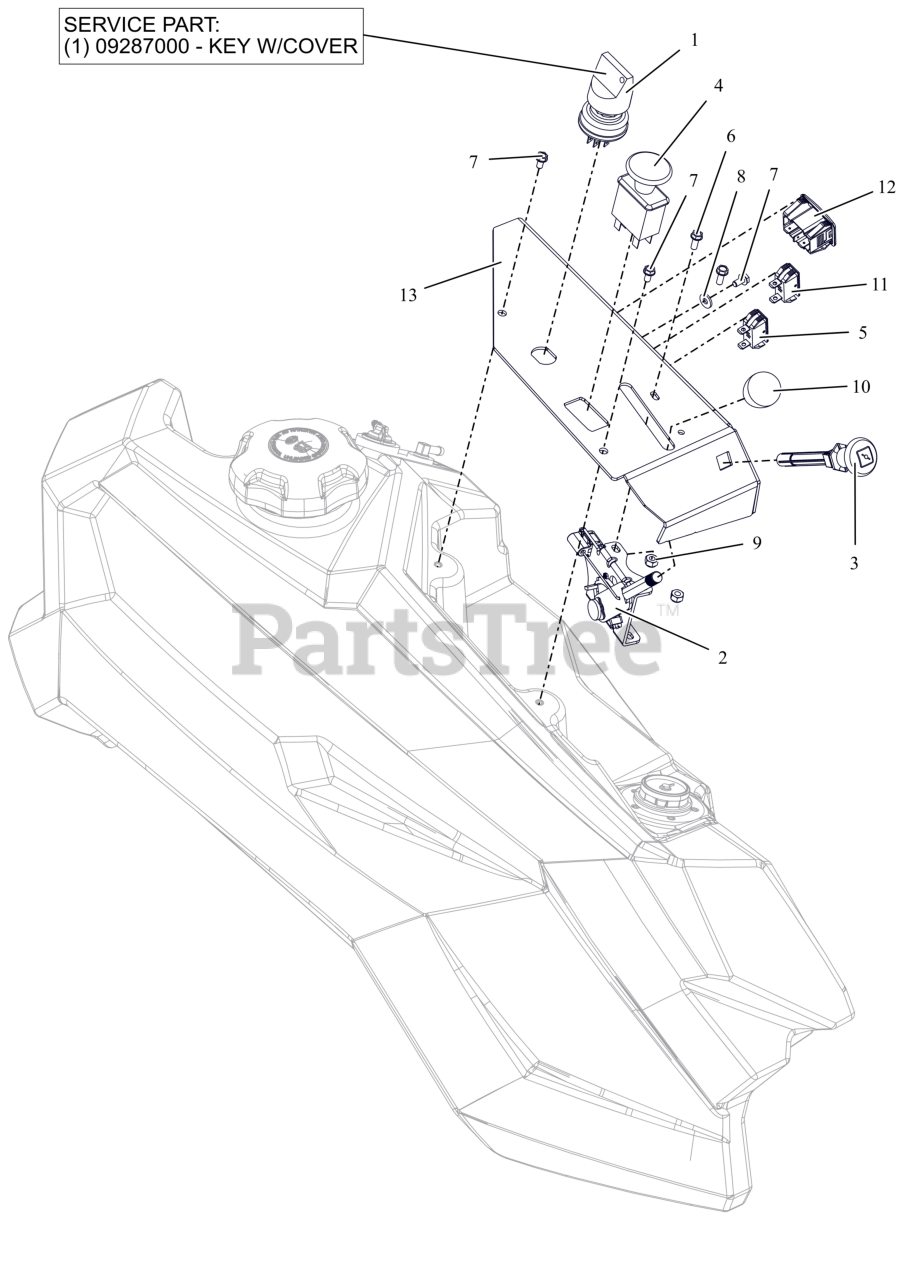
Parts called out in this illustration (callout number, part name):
1	SWITCH, IGNITION
1	KEY, W/ SHIELD
2	CABLE, PRO-CTRL 46.00"
3	CABLE, CHOKE (SNAP IN)
4	SWITCH, CLUTCH
5	LIGHT, INDICATOR (RED)
6	BLT, HWH #10-24X.50 ZCC
7	SCR-MCH 10-24X.38 HWHSTAINLESS
8	WSHR-FL-STL .196X.50X.06 ZC120
9	NUT-LK-NYL #10-24 G2 ZCC
10	KNOB-CONTROL-BLACK .38-16X.50
11	LIGHT, INDICATOR (RED)
12	HOUR METER
13	PANEL- RH CONTROL (RED)
